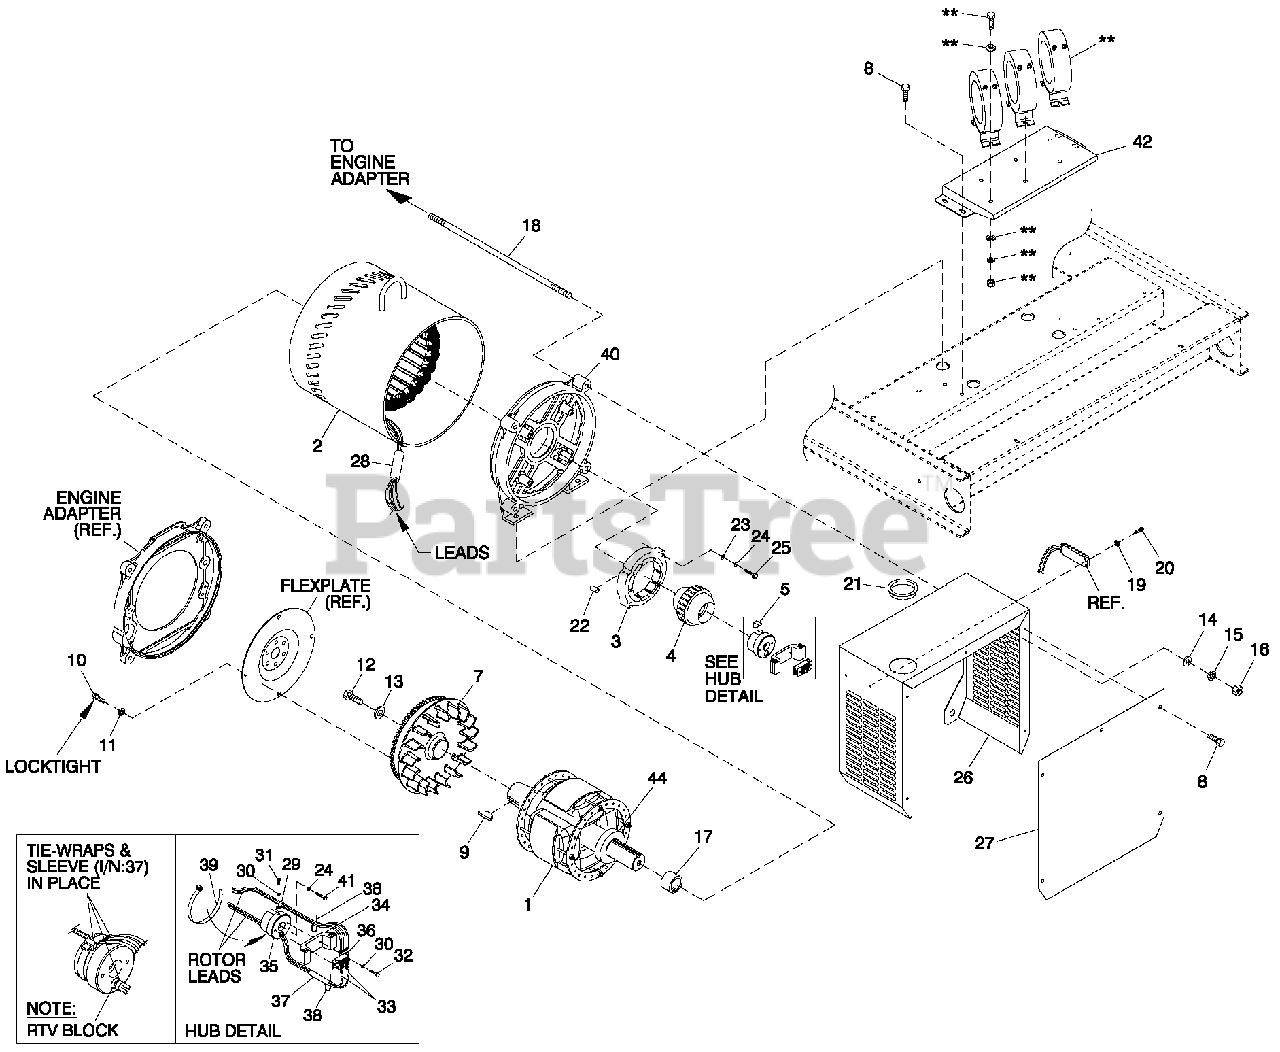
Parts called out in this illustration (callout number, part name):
1	ROTOR 390 70AB3 CPL
2	STATOR 390 70AB3 CPL
3	EXITER FIELD 2"LG SPD CONN
4	ASSY EXCITER 2 .00" STK
5	KEY SQ 3/8 X 3-1/4 STEEL
7	ASSY FLYWHEEL CPL
8	SCREW THF M6-1 X 16 N WA Z/
9	KEY WOODRUFF #E
10	SCREW HHC M10-1. 50 X 16 G10
11	WASHER LOCK M10
12	SCREW HHC M16-2. 0X4 5G8 .8
13	SPACER .69 X 2.75 X .37 ST/ZNC
14	WASHER FLAT M14
15	WASHER LOCK M14
16	NUT HEX M14-2.0G8YEL CHR
17	COLLAR SLIP FIT 390 MM
18	STUDM14-2.0X650 G5ZINC
19	WASHER LOCK #6
20	SCREW PHTT #6-32 X 1/2 ZYC
21	BUSHING SNAP SB-2 .5-31
22	PIN DOWEL 1/2 X 1-1/4
23	WASHER FLAT M12
24	WASHER LOCK M12
25	SCREW HHC M12-1.75 X 80 G10 .9
26	SHIELD ALT EXCITER 390
27	COVER EXCITER SHIELD
28	SLEEVE RUBBER
29	CLAMP VINYL .312 X .203 Z
30	WASHER SHAKEPROOF INT #8
31	SCREW HHM #8-32X3/8
32	SCREW HHM #8-32X7/8
33	LUG RT-ANG #10/10-12
34	BRIDGE SUPPORT DIODE 15"
35	CAP END ROTOR 390MM
36	ASSY BRIDGE RECTIFIER
37	SLEEVING UL #0 .330 ID (3" LG)
38	TIE WRAP UL 3 .9"X. 10" BLK
39	TIE WRAP UL 17 . 7X.35 BLK HT
40	REAR BEARING CARRIER
41	SCREW HHC M12-1.75 X 60 G10 .9
42	MOUNT CT'S 5. 4L&6 . 8L
43	BUSHING SNAP SB-2 .5-31
44	BEARING BALL 6212 SEALED
